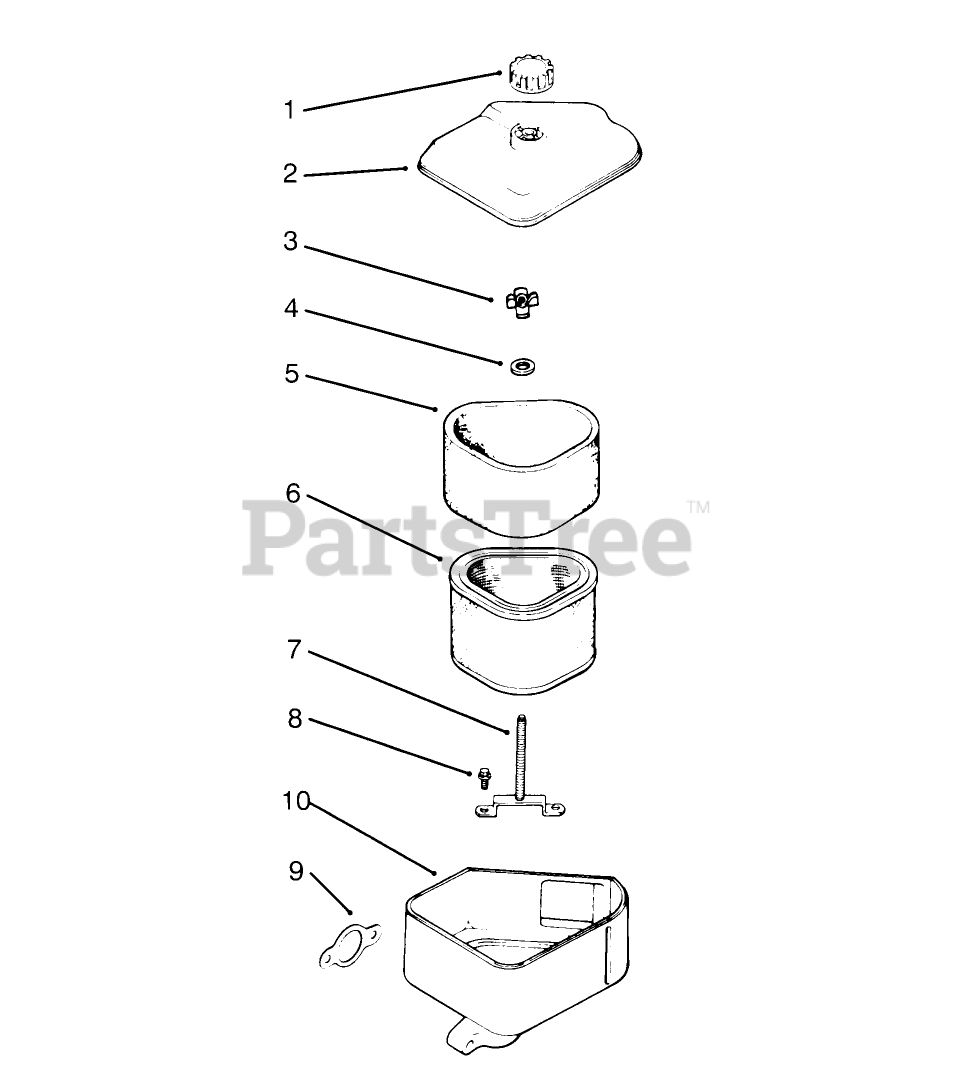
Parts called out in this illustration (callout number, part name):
1	Knob-Air Cleaner Cover (Only On: 72042, 72043, 72062, 72063)
2	Cover-Air Cleaner (Only On: 72042,72043,72062,72063)
3	Nut-Wing
4	Washer
5	Element-Air Cleaner (Only On: 72042, 72043, 72062, 72063)
6	Precleaner-Element (Only On: 72042,72043,72062,72063)
7	Stud-Mounting Plate (Only On: 72042, 72063, 72062, 72043)
8	Screw-Mounting Plate (Only On: 72042, 72043, 72062, 72063)
9	Gasket-Air Cleaner (Only On: 72042, 72043, 72062, 72063)
10	Base-Air Cleaner (Only On: 72042, 72043, 72062, 72063)
